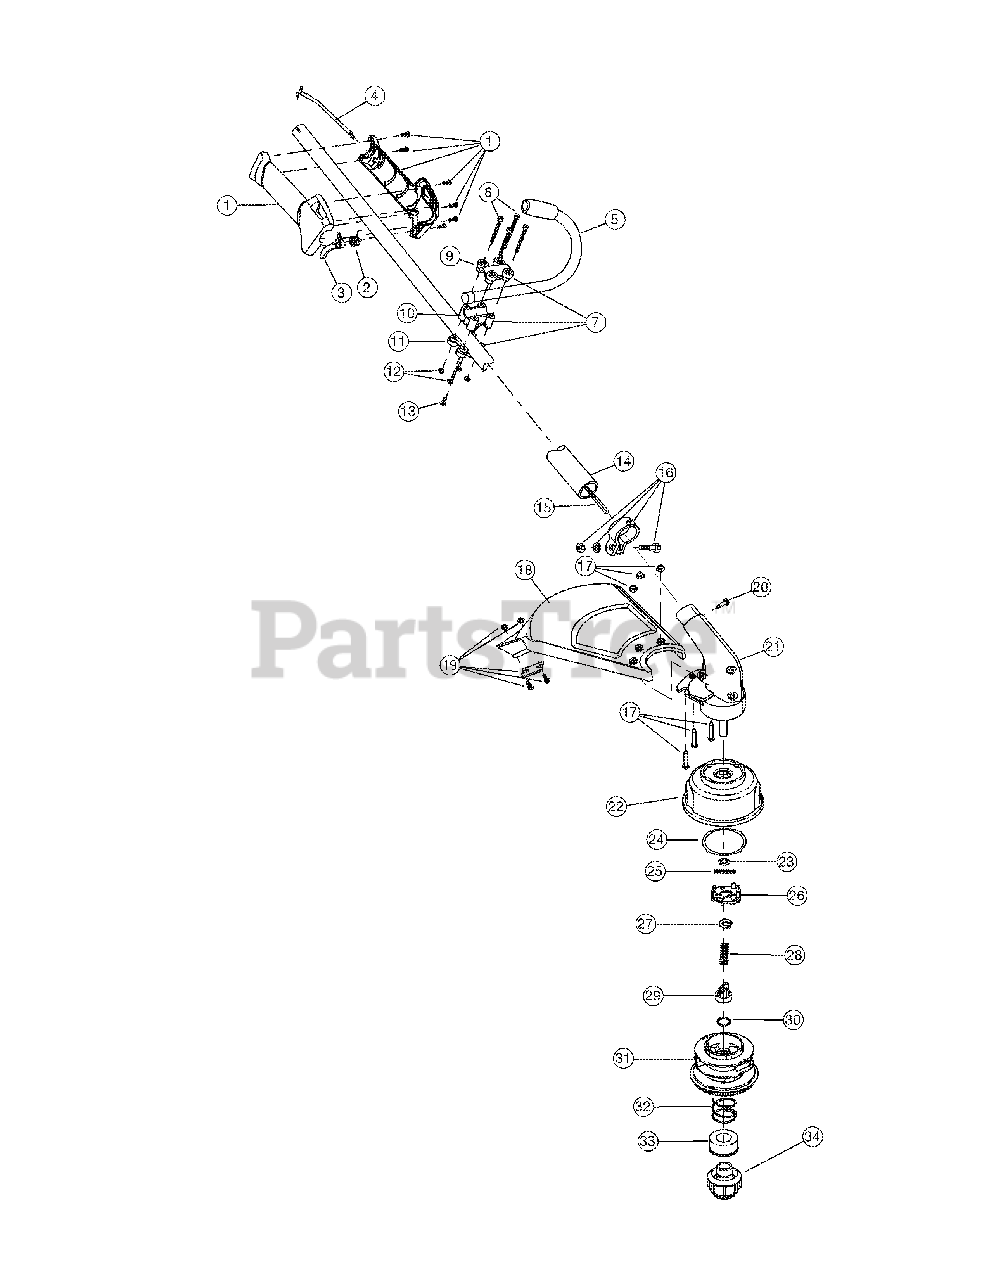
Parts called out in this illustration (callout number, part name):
1	Throttle Housing Assembly (includes 2 & 3)
2	Throttle Trigger Spring
3	Throttle Trigger
4	Throttle Cable
5	J-Handle Assembly
7	Handle Bracket Assembly (includes 8-13)
9	Upper Handle Clamp
10	Middle Handle Clamp
11	Lower Handle Clamp
13	Anti-Rotation Screw
14	Drive Shaft Housing Assembly
15	Flexible Drive Shaft
16	Lower Clamp Assembly (includes 20)
17	Guard Mounting Screw Assembly
18	Guard Assembly (includes 19)
19	Blade Assembly
20	Anti-Rotation Screw
21	Gearbox Assembly (includes 22)
22	Outer Spool Assembly (includes 23)
23	Retainer
24	Thrust Washer
25	Small Spring
26	Slider
29	Plunger
31	Inner Reel
32	Large Spring
33	Foam Seal & Washer
34	Bumb Head Knob Assembly (includes 32 & 33)
